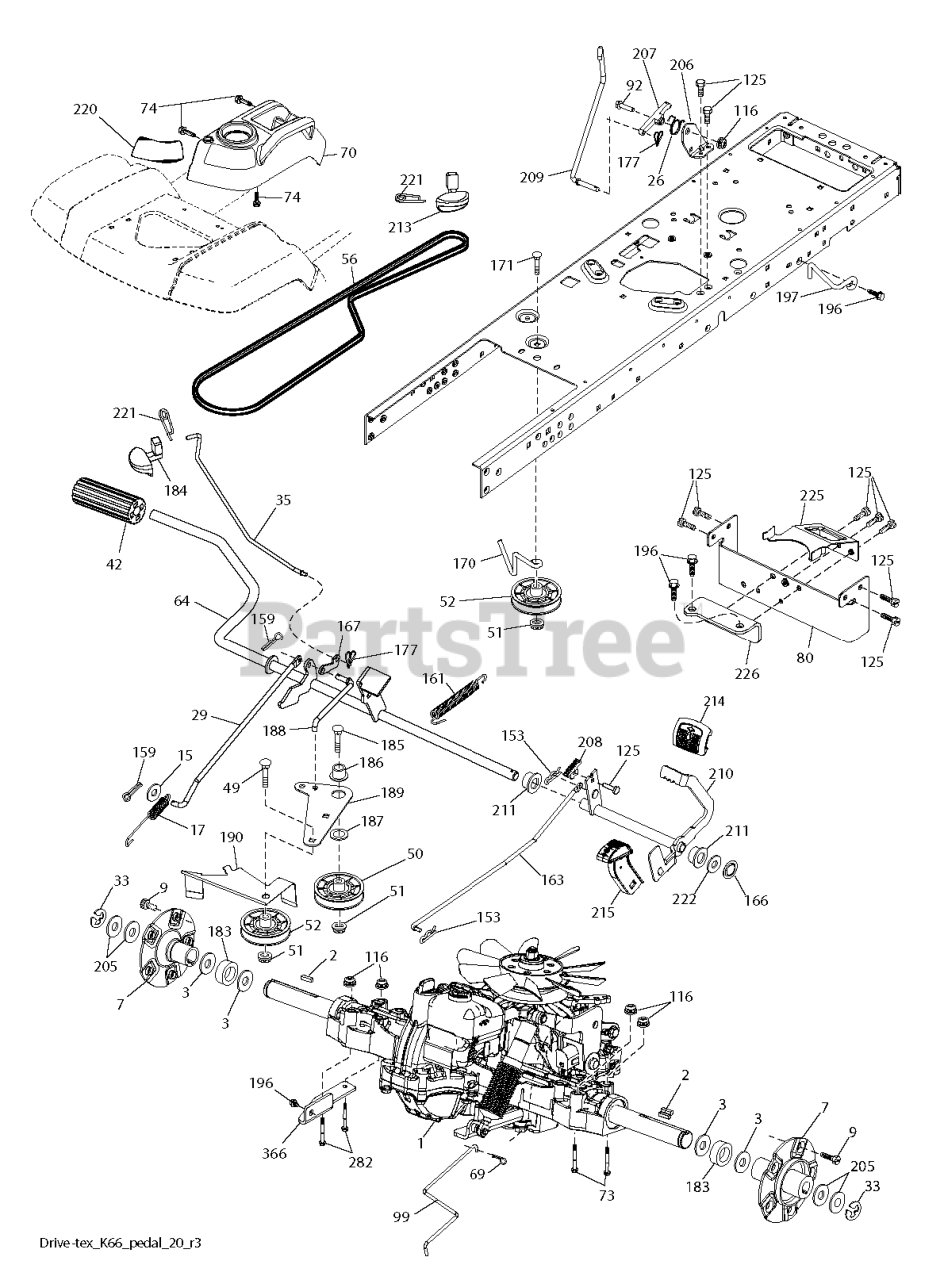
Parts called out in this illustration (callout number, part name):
1	ABSORBER
2	KEY, 1/4 SQ X 1 1/4
7	HUB.PNT.GT.PM.1IN.AXLE.E-DIP
9	Bolts
9	HUB BOLT
15	WASHER
15	WASHER PLAIN WASHER 3/8 X 0.08
17	SPRING.BRAKE.K46
26	SPRING.RETURN.CRUISE
29	ROD.BRAKE.K66
33	E RING HYT
35	ROD .BRAKE. PARKING. GT. HUSQ.
35	ROD ROD.PARKINGBRAKE.GT.HUSQ/P
42	PEDAL COVER
49	BOLT
49	Bolts
50	IDLER.FLAT.910.OFFSET
51	NUT LOCK FLG 3/8-16 UNC
52	IDLER.V-GROOVE.910.OFFSET
56	BELT.DRIVE.T2.K66
64	SHAFT.ASM.PEDAL.BRK.CNTR
69	HAIRPIN.SOFT.ZINC.059X1.125
70	CONSOLE.ASM.RH.GT.FC.HUSQ
73	Bolts
73	BOLT HEX 5/16-18 GR 5
74	Screws
74	SCREW.HI-LO.CONSOLE
80	STRAP.PNT.TORQUE.K66.EDIP
99	ROD.BYPASS.K66
125	SCREW
153	RETAINER M
159	COTTER PIN
159	Pins
161	SPRING, RETURN LT
163	ROD.PEDAL.CONTROL
166	NUT.PUSH.625
167	LATCH.BRAKE.SPRING
170	KEEPER.V-IDLER.CENTER.
177	PIN COTTER;LOCKING;BOWTIE;1IN
177	RETAINER CLIP
177	GSPW Retainers
183	SPACER.SPLIT;1.00.ID 1.75"
183	SPACER.SPLIT.1.000IDX1.75
184	HANDLE.PARKING.BRAKE.H (BLK)
186	SPACER.RETAINER
188	LINK.CLUTCH.GROUND DRIVE.LONG
189	BELLCRANK.GROUND.DRIVE.TEX.
190	KEEPER.BELLCRANK.DRIVE
196	SCREW 3/8-16X1
197	BRKT.42.FCS.CLUTCH.ANTIROTATIO
197	Stop
197	CLUTCH.ANTIROTATION.WIREFORM.
206	BRACKET.MOUNT.CRUISE.LATCH
207	LATCH.CONTROL.CRUISE.TEX
207	Latch
208	Gears
208	GEAR.SECTOR.CONTROL.CR
209	ROD.CONTROL.CRUISE.GT.
209	ROD ROD.CRUISECONTROL.GT.HUSQ/
210	ROCKER.ASM.PEDAL.CONTR
211	BEARING.NYLON
213	KNOB.CONTROL.CRUSIE.HU
214	PEDAL.FORWARD.PAD.TEX
215	PEDAL.COVER.REVERSE.CRD.X428BK
220	REFLECTOR.RH.TEX GT
221	RETAINER.SPRING.CLIP.H
222	WASHER 21/32 X 1-1/4 X 10 GA.
225	KEEPER.BELT.TRANSAXLE.K66
226	BRACKET.MOUNT.TORQUE.K66.TG
282	BOLT HEX FLGHD 5/16-18X3 GR. 5
366	BRACKET REINFORCEMENT BLACK. E
366	BRACKET.REINFORCEMENT
366	BRACKETS
